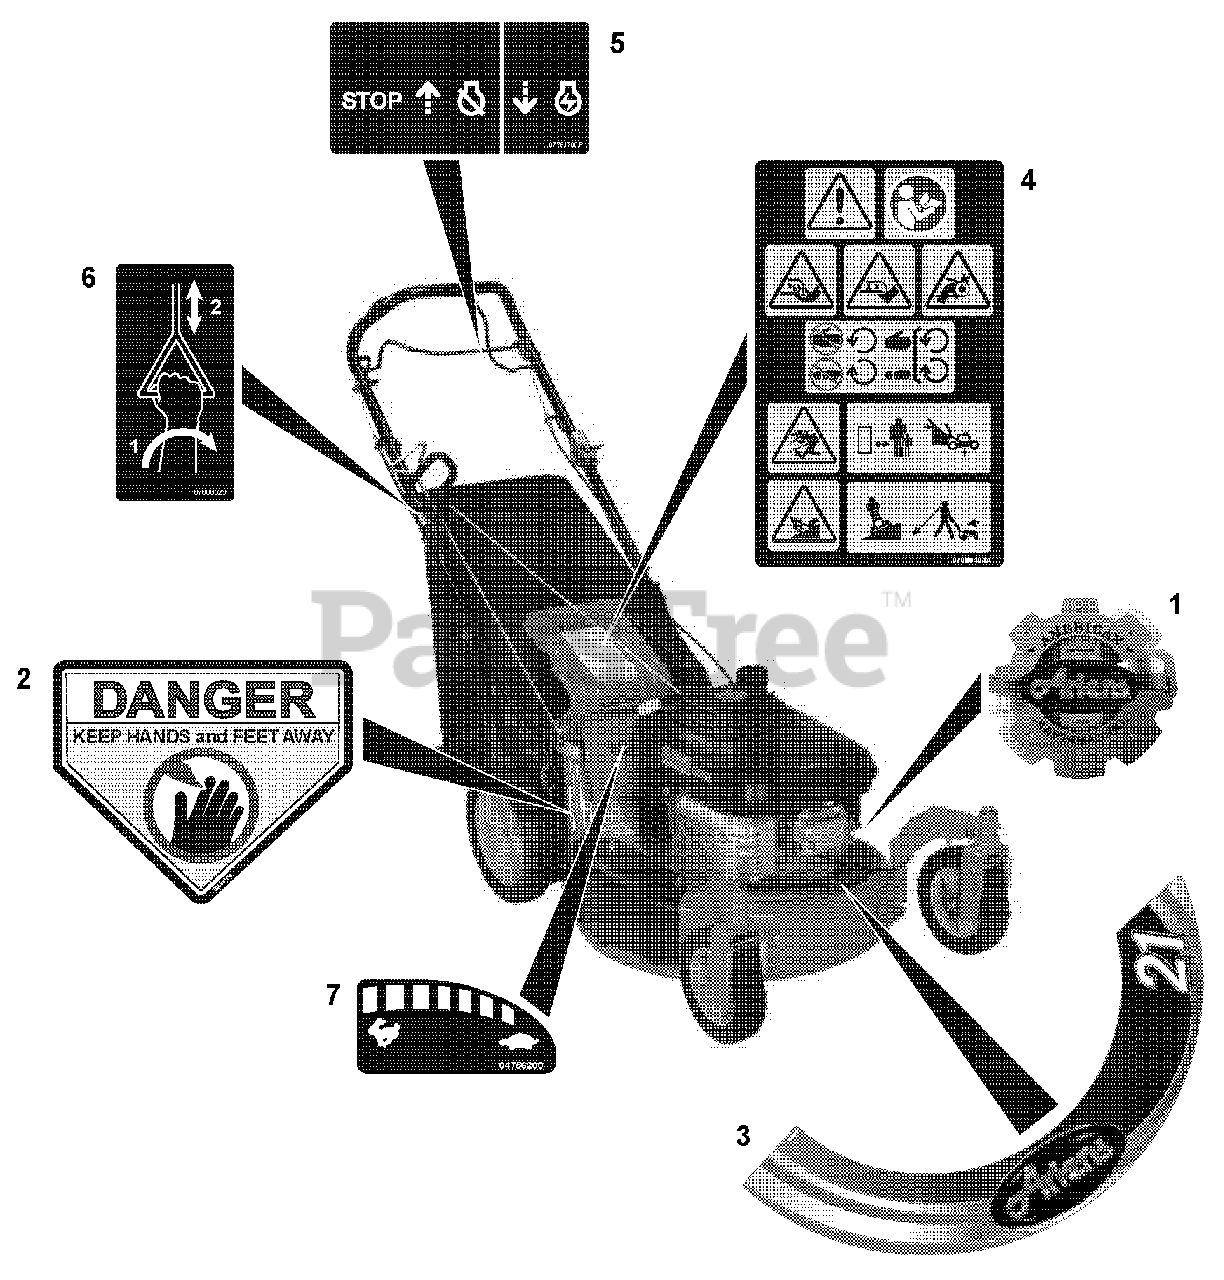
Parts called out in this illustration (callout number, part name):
1	Decal, Ariens Heritage - Small
2	DECAL, DANGER
3	DECAL, ARIENS CLASSIC 21 DECK
4	DECAL,MAIN SAFETY_WAW LM
5	DECAL - ENGINE CONTROL
6	DECAL, SPEED SELECT ROD
7	DECAL, SPEED SELECT
